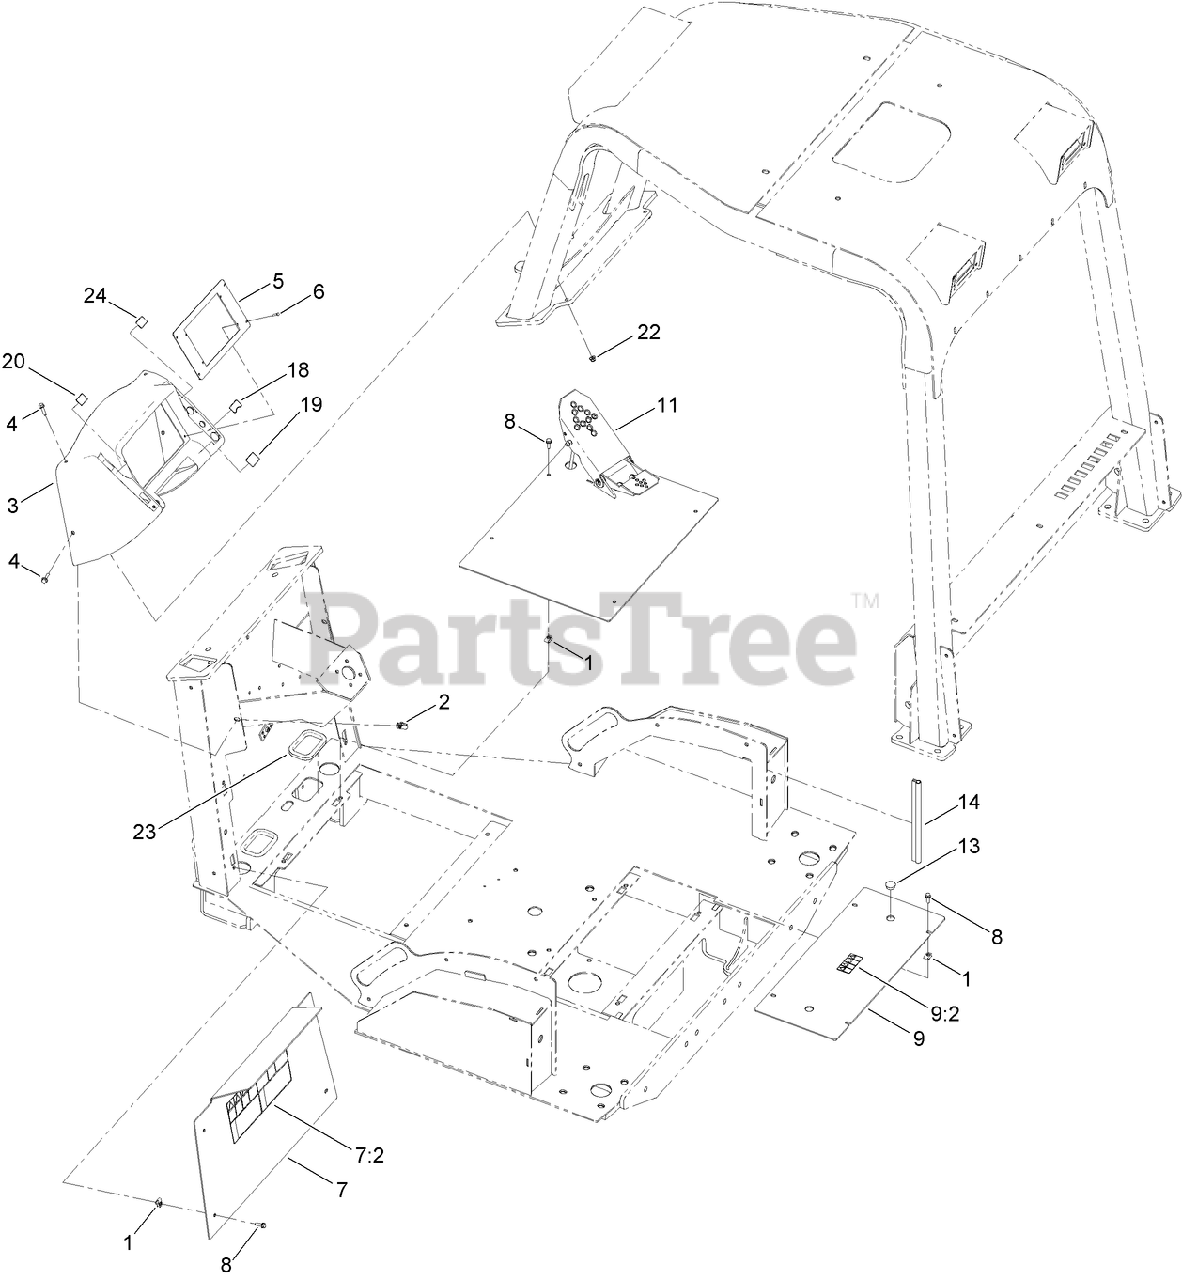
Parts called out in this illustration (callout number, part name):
1	NUT-CLIP, U
3	DASH-PANEL
4	SCREW-HHF
5	PLATE-MOUNT, DISPLAY
6	SCREW-HH
7	KICK PANEL ASM
7:2	DECAL-SAFETY
8	SCREW-HHF
9	BATTERY COVER ASM
9:2	DECAL-WARNING, BATTERY
11	PEDAL ASM
13	PLUG-DOME
14	SEAL-Hood
18	DECAL-AUX POWER
19	DECAL-IGNITION
20	DECAL-LOCK, DIFFERENTIAL
22	NUT-LOCK, HHF
23	TRIM-BATTERY
24	DECAL-BRAKE, PARKING
